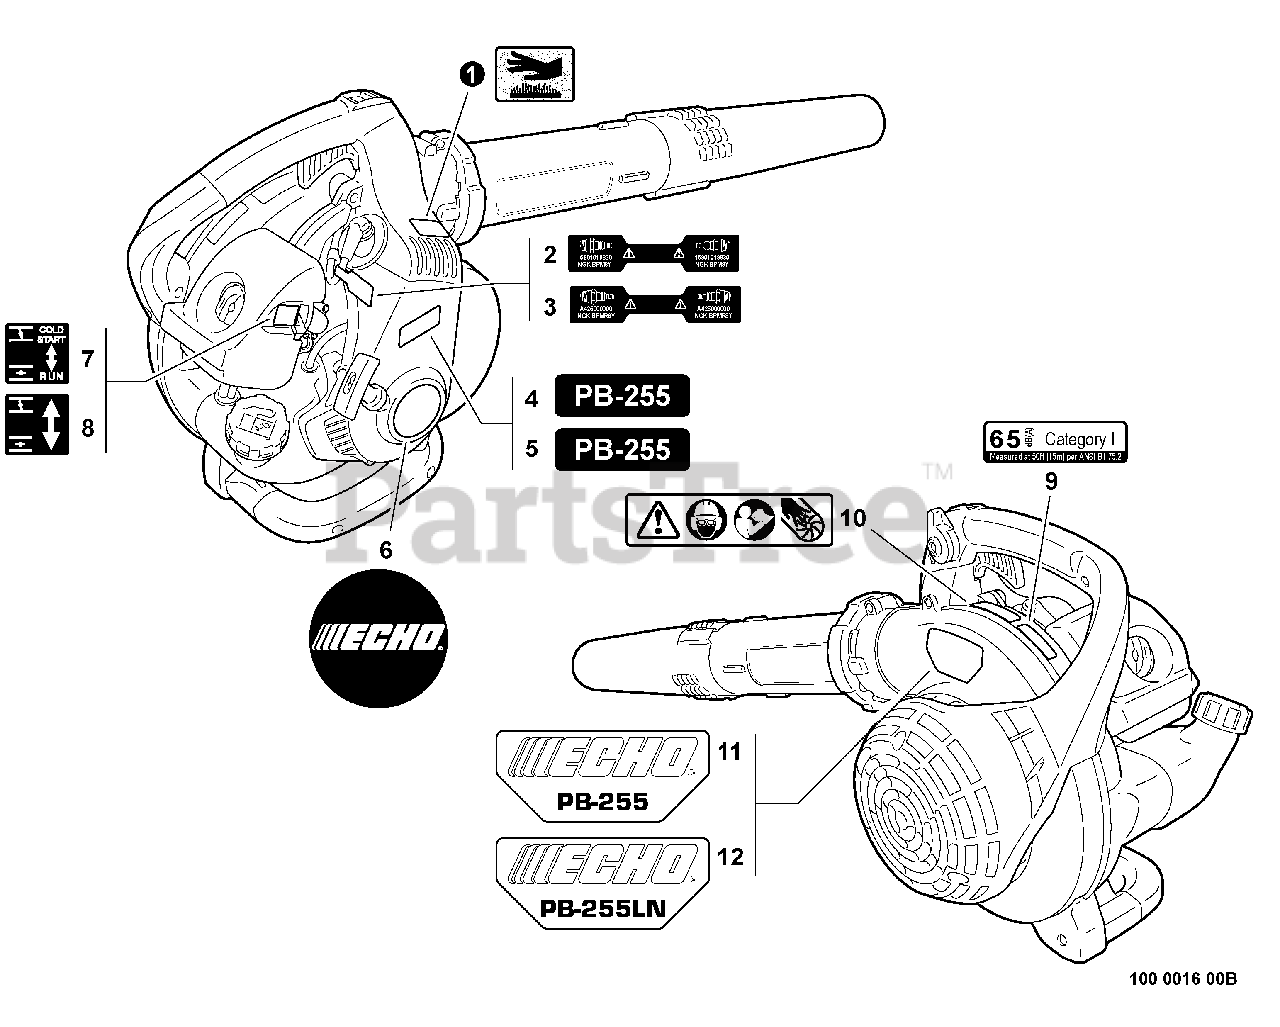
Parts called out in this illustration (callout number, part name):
1	LABEL, CAUTION - HOT
2	LABEL, SPARK PLUG - BPM8Y
3	LABEL, SPARK PLUG - BPMR8Y
4	LABEL, MODEL
5	LABEL, MODEL PB-255LN
6	LABEL, RECOIL STARTER
7	LABEL, CHOKE
8	LABEL, CHOKE
9	LABEL, NOISE
10	LABEL, CAUTION - ISO
11	LABEL, MODEL
12	LABEL, ECHO PB-255LN
